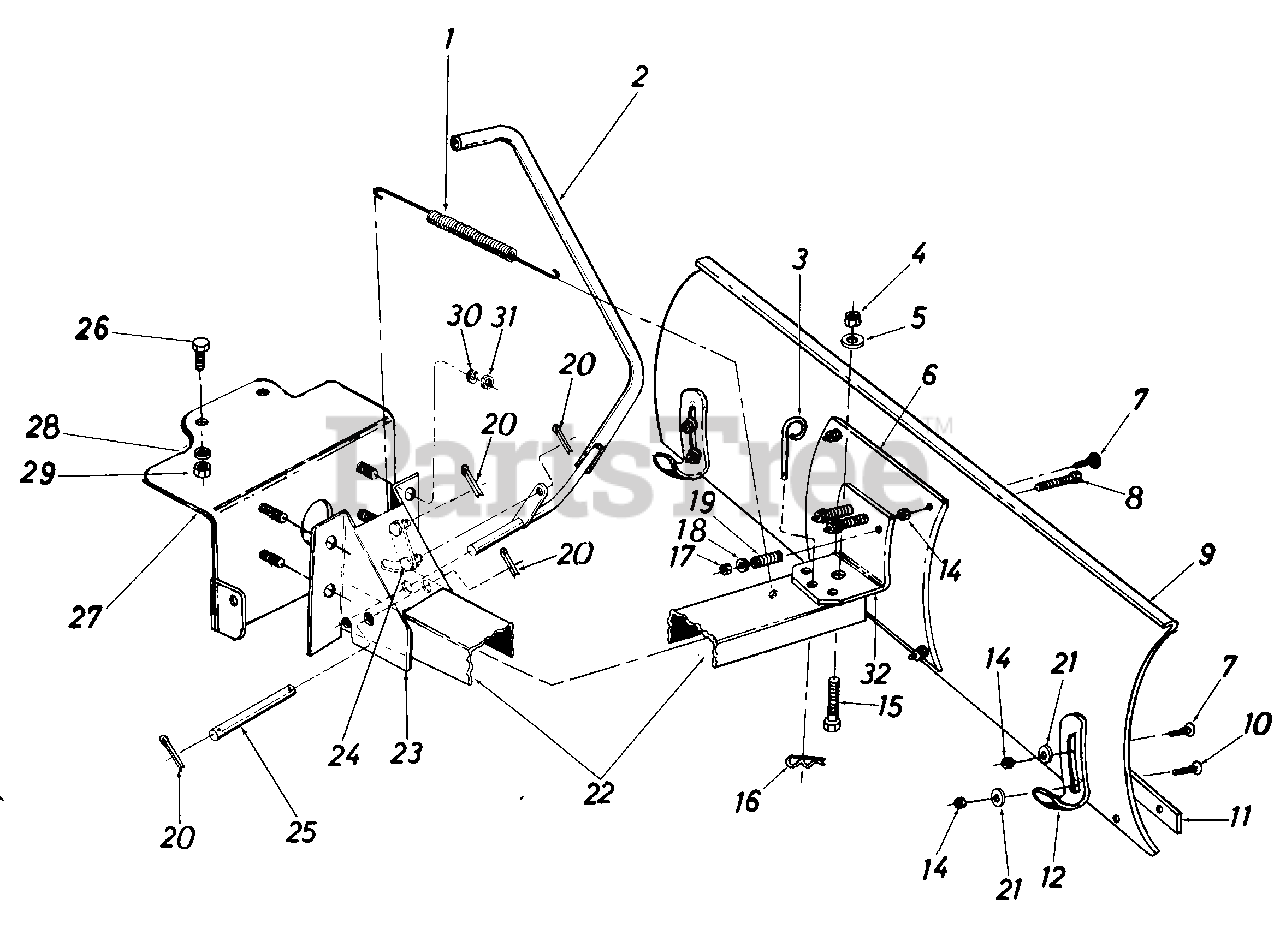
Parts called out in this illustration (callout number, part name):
1	Extension Spring
2	Lift Handle Ass'y.
3	Pivot Lock Pin
4	Hex Cent. L.-Nut 1/2-13 Thd.
5	Fl.-Wash. 17/32 I.D. x 1.25" Lg.
6	Reinforcement Plate
7	Carriage Bolt 5/16-18 x .75" Lg.
8	Hex Scr. 3/8-16 x 3.75" Lg. Grade 5
9	42" Blade
10	Carriage Bolt 5/16-18 x 1.00" Lg.
11	42" Wear Plate
12	Shoe Skid
14	Hex Cent. L.-Nut 5/16-18 Thd.
15	Hex Scr. 1/2'-13 x 1.25" Lg.
16	Hair Pin Cotter
17	HexCent. L.-Nut3/8-16Thd.
18	Fl.-Wash. 3/8" I.D.
19	Compression Spring
20	Cotter Pin 1/8" Dia. x 1.00" Lg.
21	Fl.-Wash. 5/16" I.D.
22	Push Bar Channel
23	Pivot Support Bracket
24	Lift Link
25	Channel Pivot Shaft
26	Hex Scr. 3/8-16 x 1.00" Lg. Grade 5
27	Support BracketAss'y.
28	L.-Wash. 3/8 I.D.
29	Hex Nut 3/8-16Thd.
30	L.-Wash. 3/8" I.D.
31	Hex Jam Nut 3/8-16 Thd.
32	SunDort Bracket
